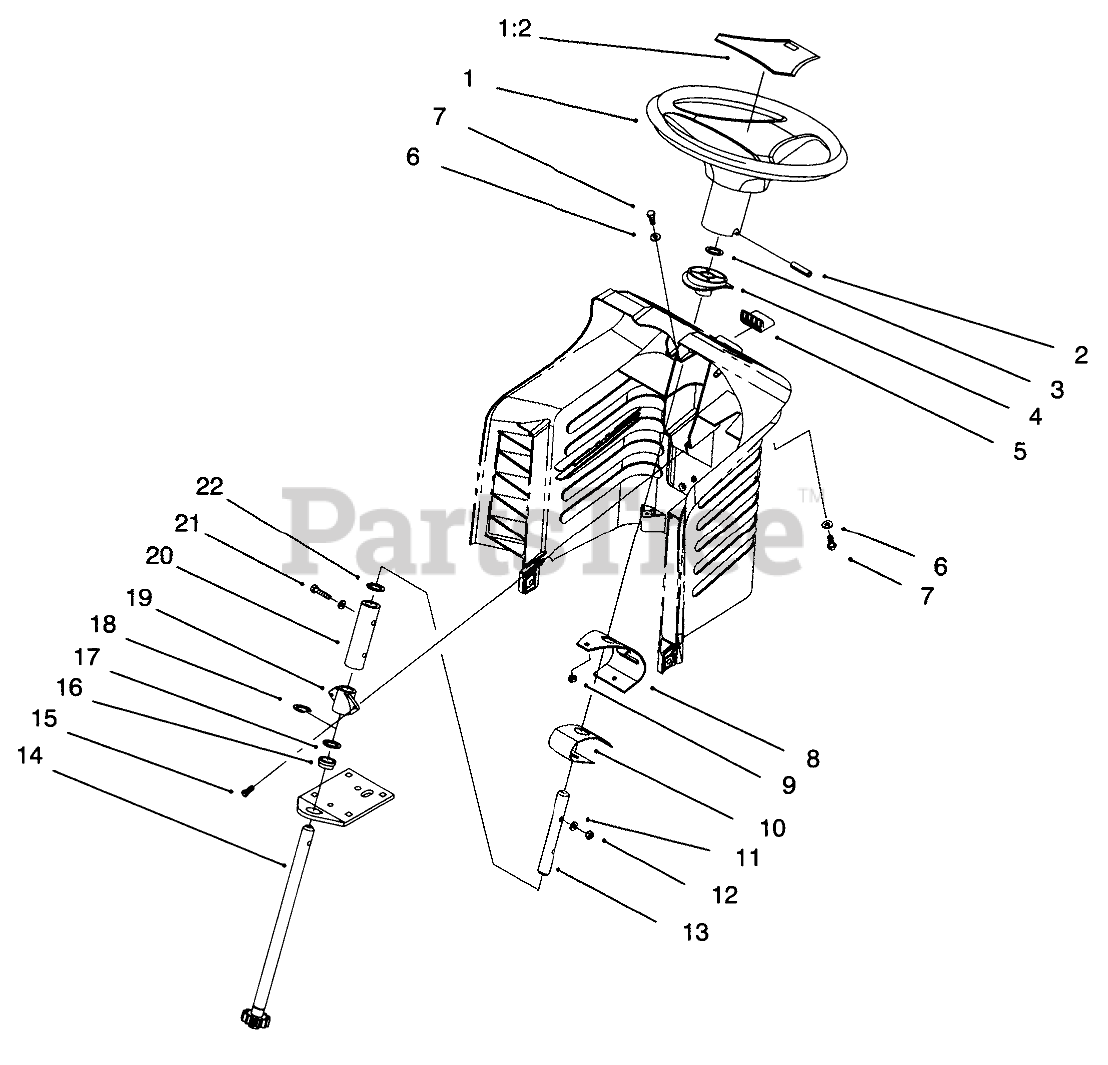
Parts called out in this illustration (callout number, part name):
1	Steering Wheel (Incl. Ref. #1:2)
1:2	COVER-WHEEL
2	PIN-ROLL
3	PUSH-ON RETAINING RING
4	BUSHING-SLIDING
5	RELEASE BUTTON
6	WASHER-FLAT
7	SCREW-HH
8	Bracket-Backup
9	NUT-LOCK, NI
10	SPRING LEAF
11	WASHER
12	NUT-LOCK, NI
13	UPPER STEERING SHAFT
14	SHORT STRG SHAFT WA
15	SCREW-SPECIAL
16	BEARING-FLANGE
17	WASHER-THRUST
18	E-RING
19	BUSHING STATIONARY
20	COUPLING, STEERING
21	SCREW-HH
22	WASHER-THRUST
